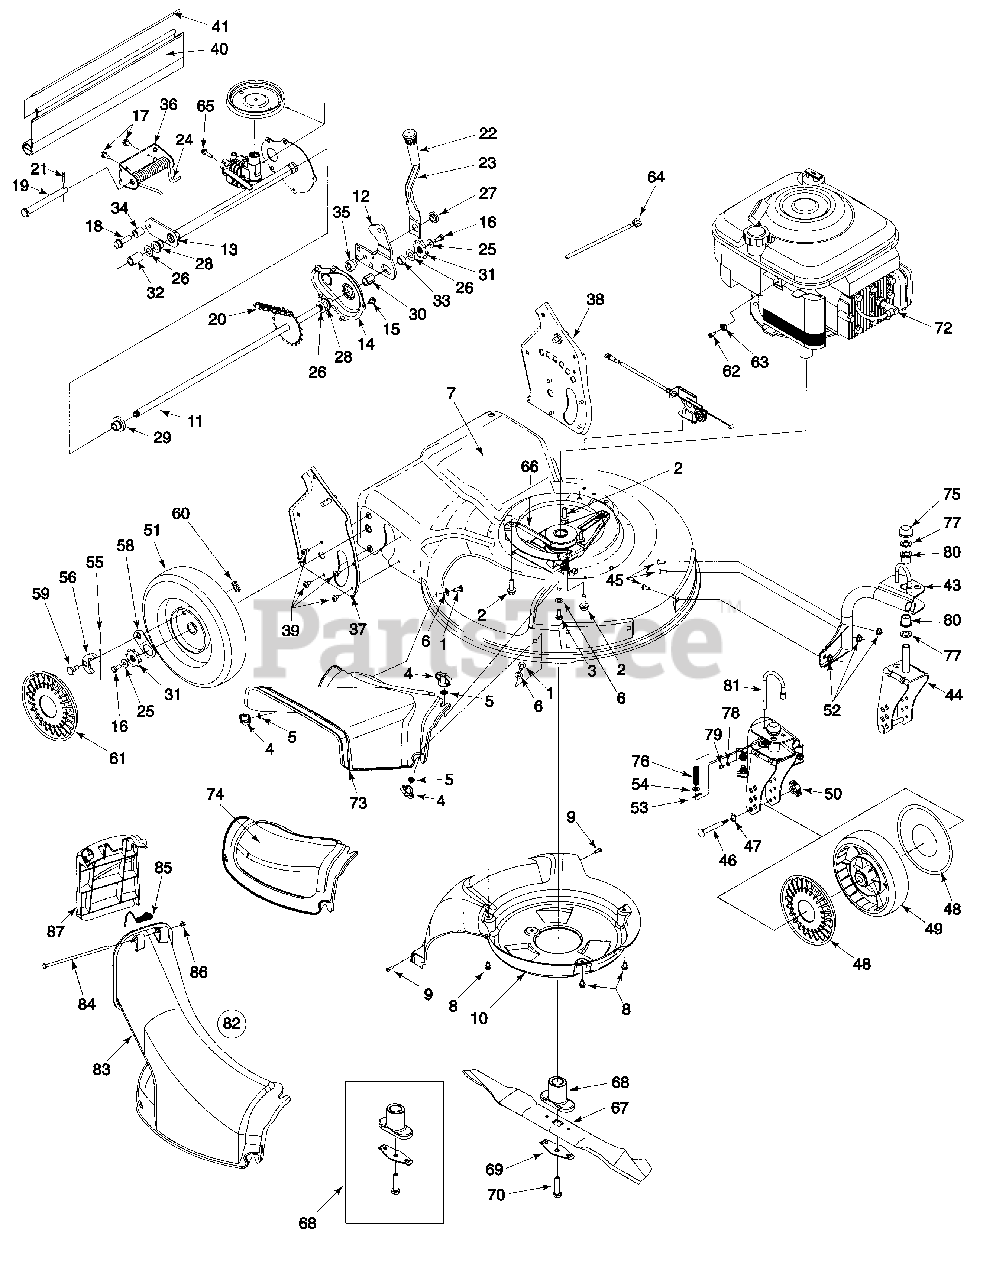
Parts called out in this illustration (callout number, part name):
1	Scr. Carr. 1/4-20 x .62
2	Scr. TT:3/8-18:1.00
3	Scr. 1/4-20 x .750
4	Wing Nut 1/4-20
5	Nut, Push .25 I.D. x .50 O.D.
6	Wash. Fl. .334 I.D. x .62 x .03
7	Deck - 21"
8	Scr. TT. 1/4-20 x .375
9	Scr. HL. 1/2-14 x .750
10	Baffle
11	Rear Axle Ass'y
12	Pivot Arm Ass'y
16	Cap Screw HH 1/4-20 x .620
17	Scr. AB 1/4-14 x .825
18	Scr. 3/8 116 x .25
19	Clevis Pin .50 Dia. x 4.82 Lg.
20	Chain-Endls. #48.500P x 24L
21	Cotter Pin .1250. D. x .75
23	Spring Lever
24	Torsion Spring
25	Bell Wash. .285 x .75 x .082
26	Fl. Wash. .508 I.D. 1.000 x .
27	Nut Shld. .825 Dia. x .165 Lg.
28	Hx . Flg. Brg. .506 I.D. x .590 L.
29	Hx . Flg. Brg. .506 I.D. x .715 L.
30	Hx . Slv. Brg. .504 I.D. x .830 L.
31	Wheel Rachet
32	Spa. .550 I.D. x/750 O.D.
33	Spa. .51 .D. x .70 O.D. x 38 L.
34	Spa. .385 x .624 x .700
35	Shld. Spa. .385 I.D. X .715 Lg.
38	Handle Brkt. Ass'y. L.H.
39	Scr. AB 1/4-14 x .500
40	Trail Shield
41	Trail Shield Wire
43	Caster Ass'y R.H.
43	Caster Ass'y L.H.
44	Brkt Ass'y
45	Carr. Bolt 5/16-18 x .62
46	Caster Axle .374 Dia x 2.50"
47	Wave Washer
48	Hub Cap, Yellow w/hole
49	Wheel 7 x 2 Link, Yellow
50	Wing Nut 1/4-20
51	Wheel 9 x 2 Link Yellow, Slv.
52	Lock Nut 5/15-18
53	Cotter Pin .072 x .12 Lg.
54	Fl. Wash. .330 x .830 x .060
55	Spring, Ratchet, Plastic
56	Pawl- R.H.
56	Pawl - L.H.
58	Ratchet Pawl Plate
59	Scr. Shld. .340 x .285
60	Top Lock Tab Weld Nut 1/4-20
61	Hubcap -Yellow
62	Screw .620 Hx . Sit. Wsh.
63	Casing Clamp, Throttle
64	Cable Tie
65	Hex Scr. 5/16-18
66	Belt
67	21" Mulching Blade
68	Blade Adapter Kit
69	Blade Bell Suport
70	Hex Bolt 3/8-24 x 2.5"Lg.
72	Spark Plug Insulator
73	Side Discharge Chute
74	Mulch Cover
75	Push Cap
76	Compression Spring
77	Fl. Wash. .5/8 I.D. x 1" O.D.
78	Fl. Wash. .203 x .403 x .
79	Fitting - Grease
80	Flange Bearing
81	Locking Pin
82	Chute Ass'y
83	Discharge Chute
84	Pivot Rod
85	Torsion Spring
86	Push Cap
87	Chute Door
